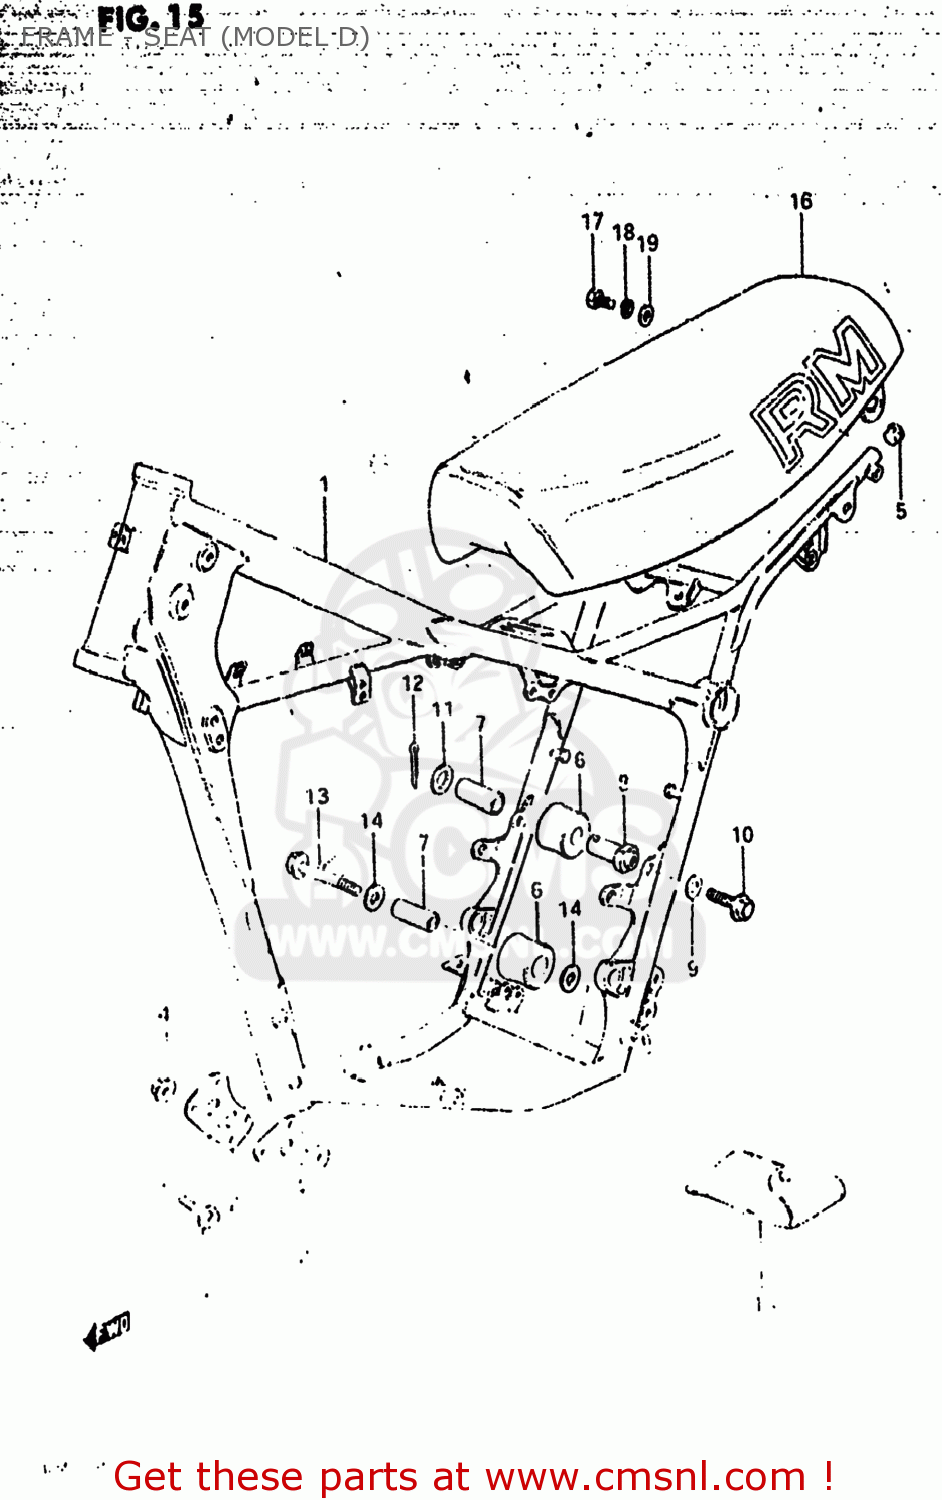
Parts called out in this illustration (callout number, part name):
1	FRAME
2	PLATE,ENGINE MOUNTING
3	BOLT(8X75)
4	NUT
5	PLUG(OD:17)
6	ROLLER,CHAIN LENGTH CONTROL
7	SPACER,CHAIN LENGTH ROLLER
8	BOSS,CHAIN LENGTH ROLL
9	WASHER
10	BOLT
11	WASHER
12	PIN 25X20
13	BOLT(8X45)
14	WASHER
15	TOOL SET
16	SEAT ASSEMBLY
17	BOLT
18	LOCK WASHER
19	WASHER
